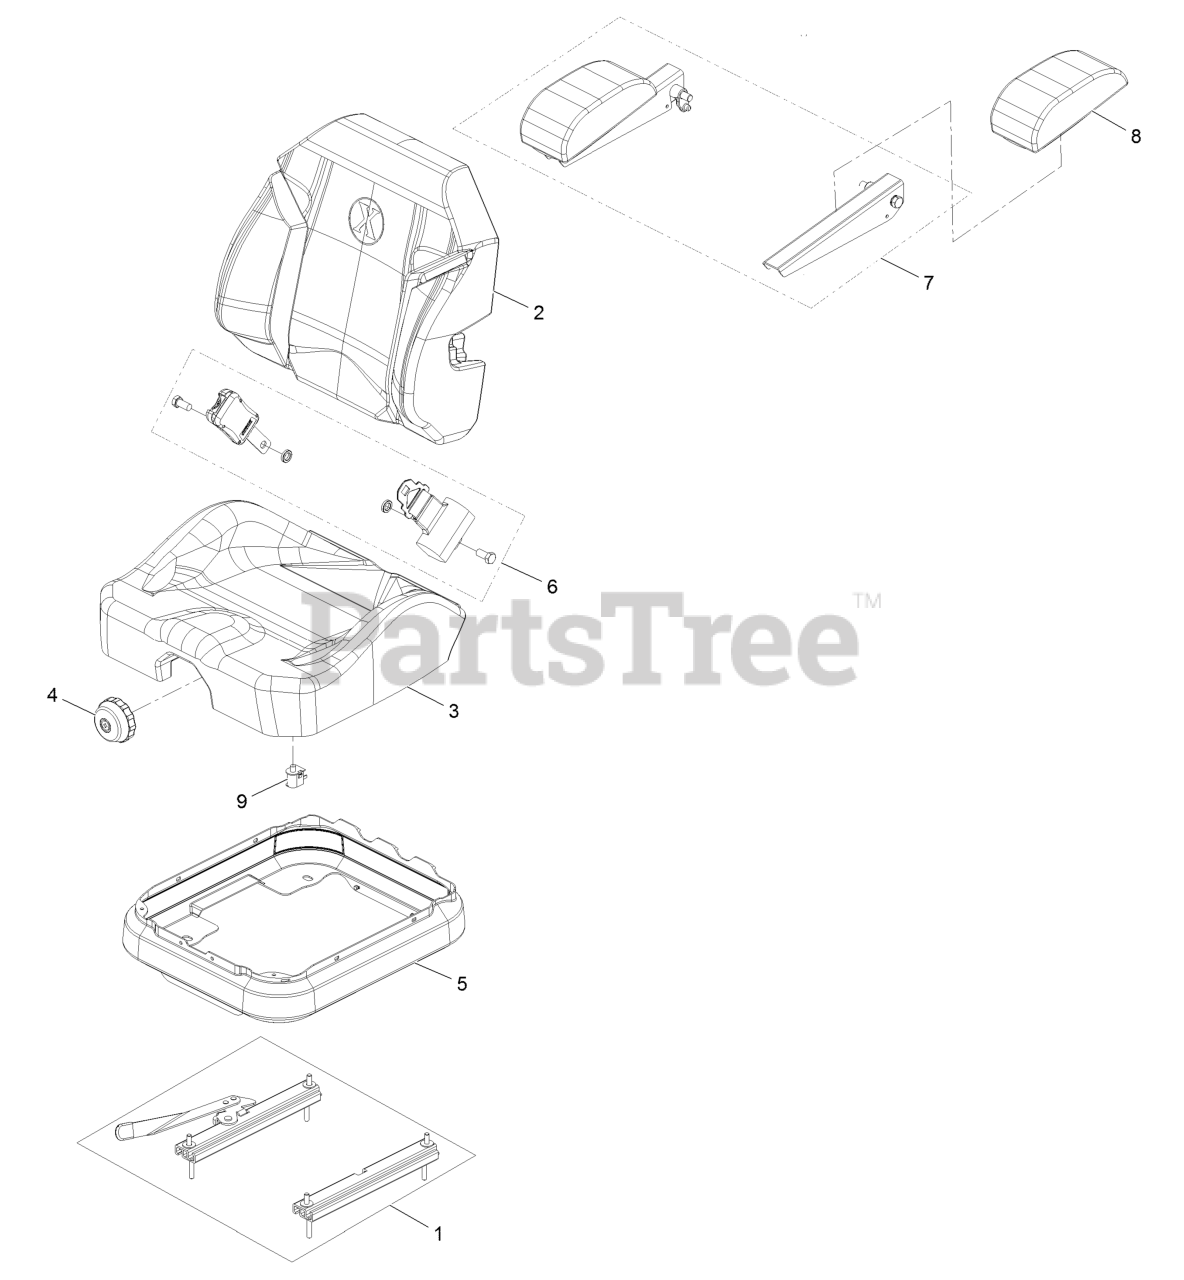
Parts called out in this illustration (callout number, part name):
1	Seat Track Set
2	Cover-Back 311463Vn500
3	Cover-Cushion 311464Vn500
4	Knob-Adjuster
5	Cover-Suspension Bellows
6	Seat Belt Service Kit
7	Kit-Arm Rest Set
8	Kit-Arm Rest Pads
